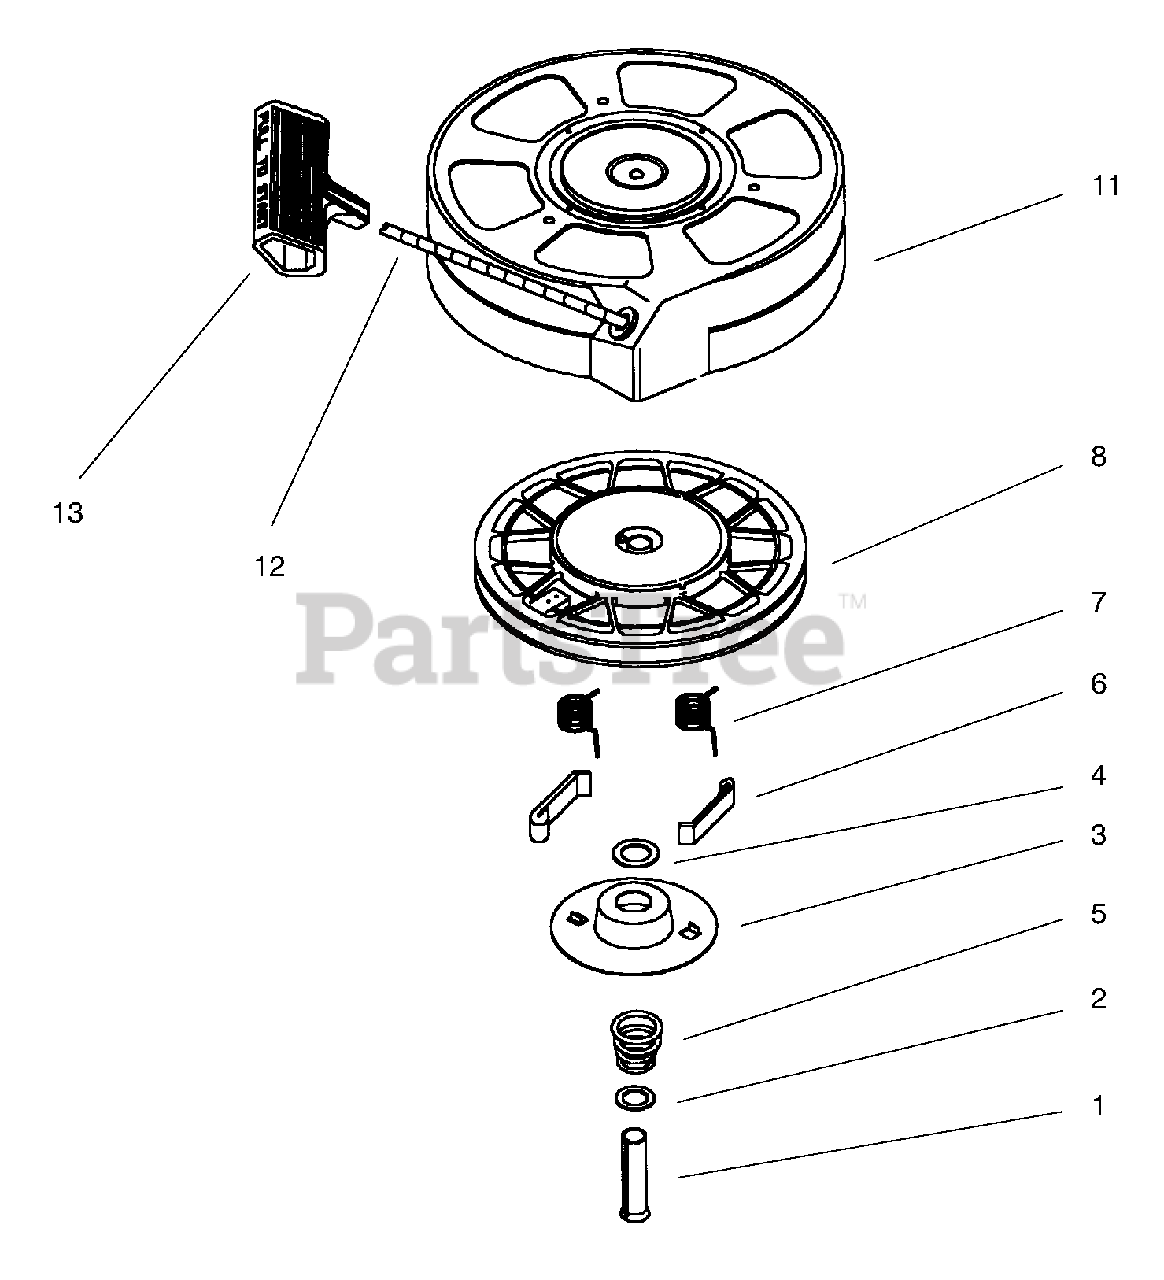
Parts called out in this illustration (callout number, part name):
1	Spring Pin (Incl. 4)
3	Retainer
5	Brake Spring
6	Starter Dog
7	Dog Spring
8	Pulley & Rewind Spring Ass'y.
11	Starter Housing Ass'y (40 degree grommet)
12	Starter Rope ( 98" X 9/64" dia.)
13	Starter Handle
